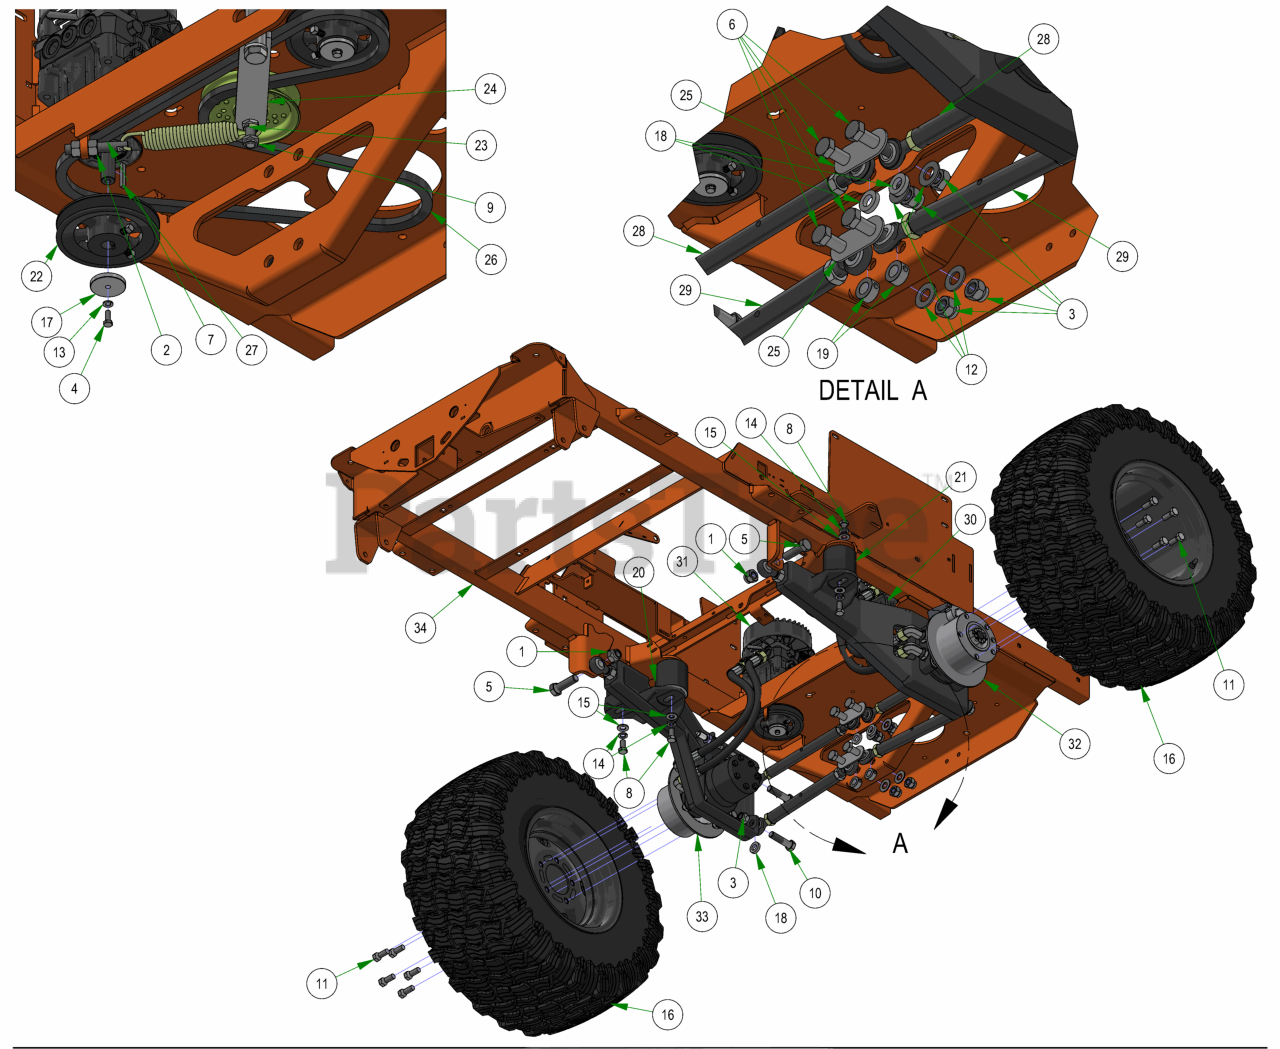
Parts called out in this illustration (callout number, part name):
1	3/4-10 NYLON INSERT LOCKNUT ZINC
2	1/2-13 HEX NUT ZINC
3	5/8-11 NYLON INSERT LOCKNUT ZINC
4	M6-1.0 X 16MM DIN 933 HEX TAP BOLT (CL 8.8) ZINC
5	3/4-10 X 2-1/2 HEX CAP SCREW (GR.5) ZINC
6	5/8-11 X 2-3/4 HEX CAP SCREW (GR.5) ZINC
7	All Thread
8	1/2-13 X 1 HEX CAP SCREW (GR.5) ZINC
9	1/2-13 NYLON INSERT JAM LOCKNUT ZINC
10	5/8-11 X 2-1/2 HEX CAP SCREW (GR.5) ZINC
11	1/2-20 x 60° Lug Bolts Zinc Grade 8
12	5/8" Flat Washer SAE Spec Grade 8
13	1/4SPLIT LOCKWASHER ZINC
14	1/2 SPLIT LOCKWASHER (GR.8) ZINC/YELLOW
15	1/2 SAE FLAT WASHER (1-1/16" OD) GR.8 ZINC YELLOW
16	2019 Assy-26x12-12 Reaper Turf -10.5" Rim
17	Rogue Pump washer
18	Spacer 1.125OD x .625 ID x .250 Length
19	5/8 SOLID SHAFT COLLAR (W/1 SET SCREW) ZINC
20	Vibration Mount-Blue Dot
21	Vibration Mount-Green Dot
22	5" PUMP PULLEY W/ SET SCREW
23	Deck Idler Spring
24	2019 Rogue Pump Idler Assy
25	2019 Suspension Gusset Outlaw
26	2019 Rogue Pump Belt 68"
27	5MM X 36MM SQ MACHINERY KEY C1018 ROUNDED ENDS
28	2019 Suspension Radius Rod Assembly
29	2019 Suspension Radius Rod Assembly
30	2021 LH ROGUE HYDRO TANK LINE ASSY
31	2021 RH ROGUE HYDRO TANK LINE ASSY
32	2019 Rouge Trailing Arm LH Assy
33	2019 Rogue Trailing Arm RH Assy
34	2023 Rogue Frame - Painted
